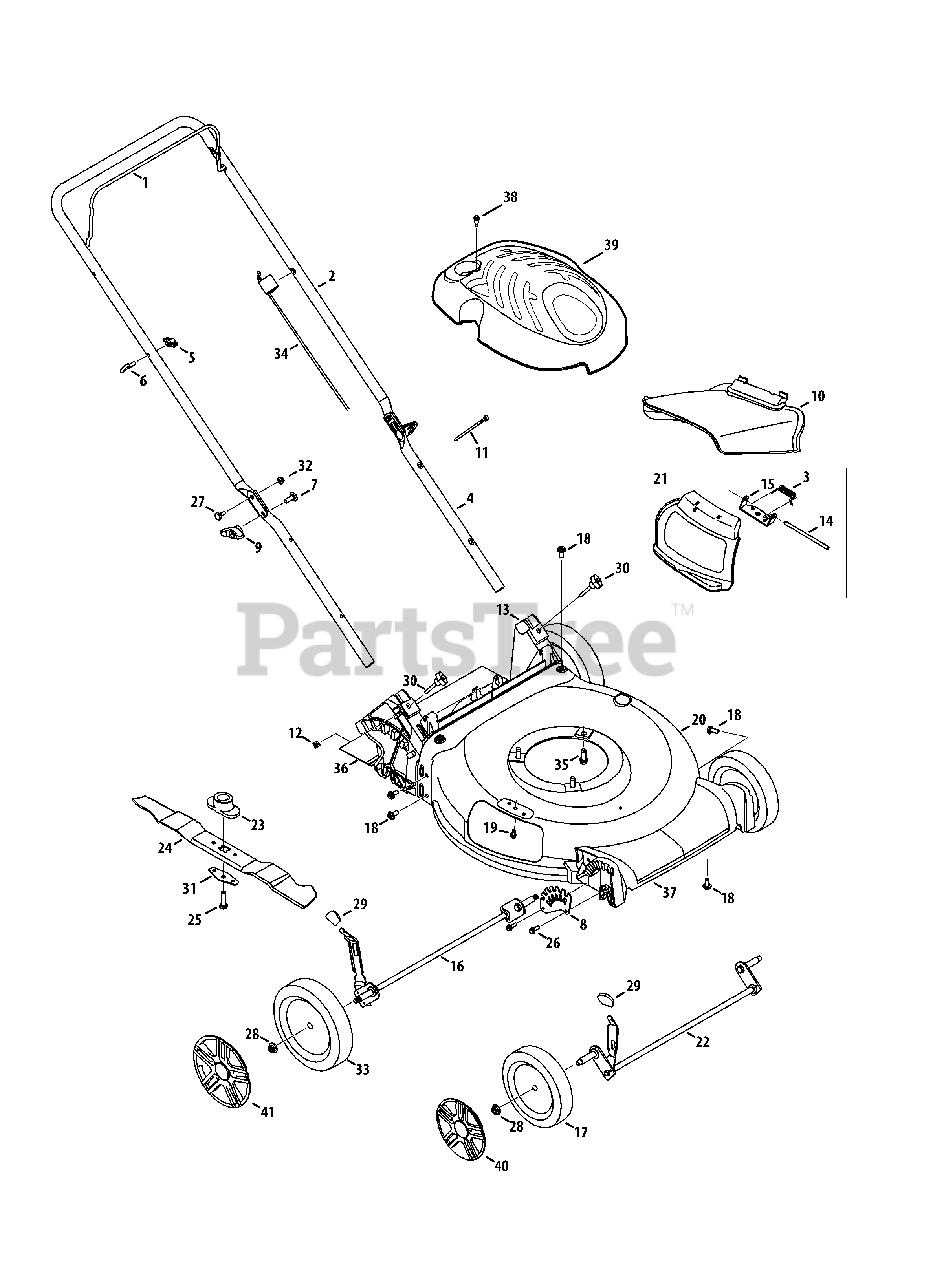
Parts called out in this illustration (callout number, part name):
1	Blade Control
2	Upper Handle, Adjustable
3	Torsion Spring
4	Lower Handle
5	Wing Nut
6	Rope Guide
7	Carriage Screw, 5/16-18
8	Front Height Adjuster Plate
9	Wing Knob
10	Side Chute
11	Cable Tie
12	Nut, Sq., 1/4-20
13	Rear Baffle
14	Hinge Pin
15	Chute Deflector Bracket
16	Rear Axle Assembly
17	Front Wheel, 7 x 2.0, Z, Black
18	Screw, 5/16-14 x .750
19	Screw, 1/4-20 x .500
20	Deck , 21" - Red
21	Hinged Mulch Plug Assembly
22	Front Axle Assembly
23	Blade Adapter, 25mm x 1.19
24	Mulching Blade
25	Screw , 3/8-24 x 1.50
26	Screw, 1/4-15 x .750
27	Sldr. Screw, .375 x .126 x 1/4-20
28	Flange Lock Nut, 3/8-16
29	Adjustment Lever Knob
30	Wing Nut
31	Blade Bell Support
32	Nut, Flange Lock, 1/4-20
33	Rear Wheel, 8 x 2.0, Z, Black
34	Control Cable 37.58"
35	TT Sems Screw, 3/8-16 x 1.0
36	Trail shield
37	Front Cover
38	Screw, HL, #12-16 x 1.00
39	Engine Shroud M1.1 Black
40	Hubcap, 7"
41	Hubcap, 8"
